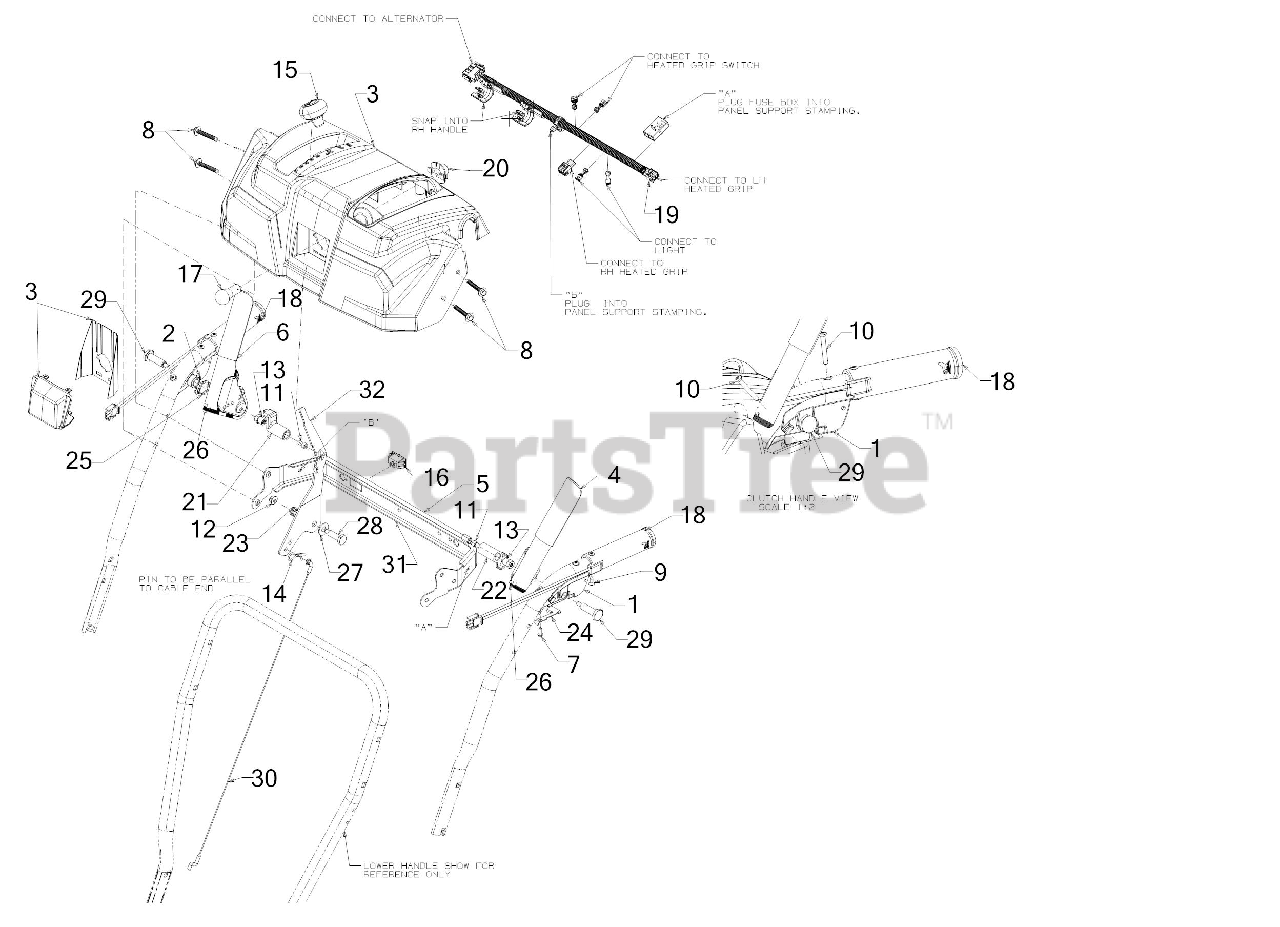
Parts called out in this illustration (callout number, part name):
1	CLUTCH LOCK HANDLE ASSEMBLY (LH)
2	CLUTCH LOCK HANDLE ASSEMBLY (RH)
3	HANDLE PANEL ASSEMBLY (TROY-BILT)
4	HANDLE ASSEMBLY (LH)
6	ENGAGEMENT HANDLE ASSEMBLY (RH) (BLACK)
7	SCREW #8-16 x .50
8	SCREW 1/4-20 x 1.625
9	SCREW #10-16 x .625
10	SCREW #10-24 x 1.375
11	SCREW 1/4-20 x .50
12	FLANGE LOCK NUT
13	HEX NUT W/PATCH
14	INTERNAL COTTER PIN
15	SHIFT KNOB
16	HEATED GRIP SWITCH
17	LAMP-#1683
19	HEATED GRIPS HARNESS
20	HEADLIGHT SOCKET
22	CLUTCH LOCK CAM
23	COMPRESSION SPRING
24	CLUTCH SPRING
25	TORSION SPRING
26	RUBBER BUMPER
27	FLAT WASHER
28	SHOULDER SCREW
29	SHOULDER SCREW .437 x 1.345 1/4-20
30	SPEED SELECTOR CABLE (PLASTIC)
